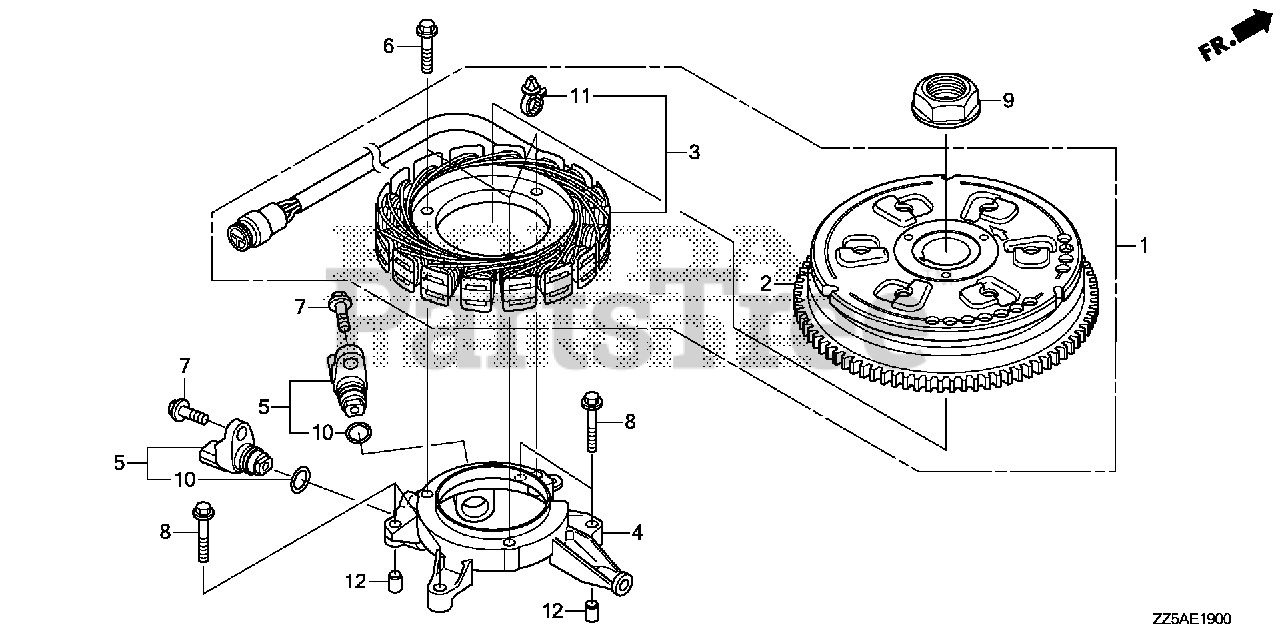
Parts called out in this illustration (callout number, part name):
1	ALTERNATOR ASSY. *TBLACK* (BLACK)
2	ROTOR *TBLACK* (BLACK)
4	BRACKET, ALTERNATOR
5	SENSOR ASSY., CRANK
6	BOLT, FLANGE (6X25)
7	BOLT, FLANGE (6X16)
8	BOLT, FLANGE (6X30)
9	NUT, SPECIAL (24MM)
10	O-RING (15X1.9)
11	CLIP, HARNESS BAND (96.9MM) (NATURAL)
12	PIN, DOWEL (8X10)
